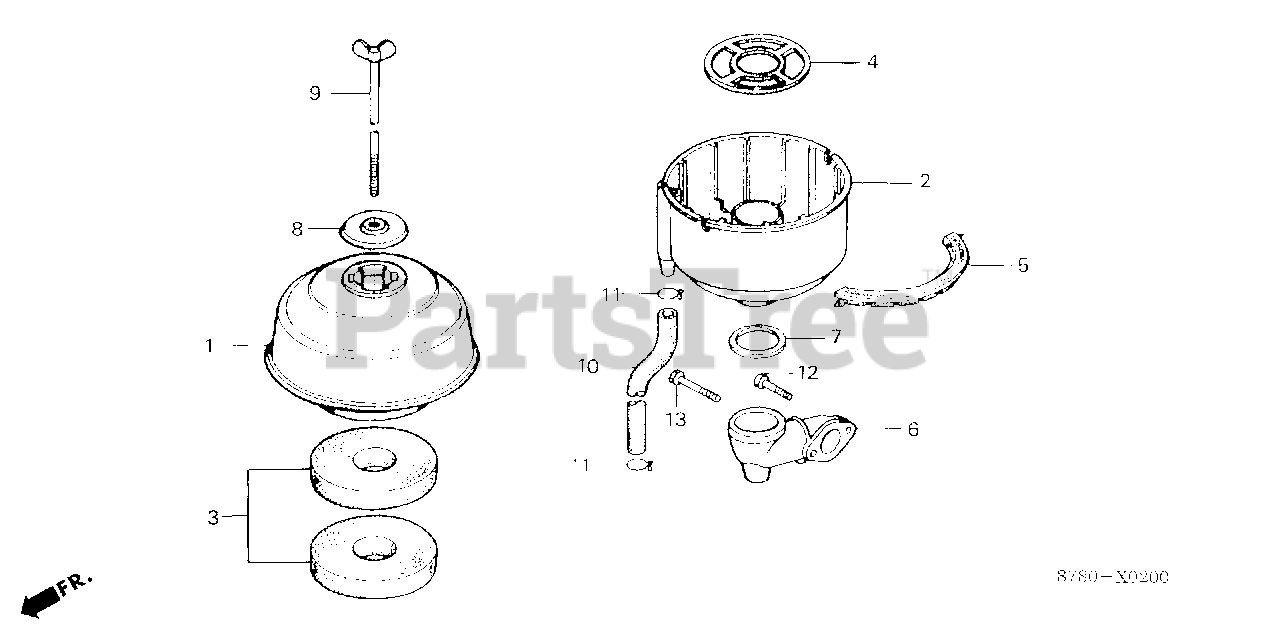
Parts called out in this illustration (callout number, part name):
1	BODY, CLEANER
2	PAN, AIR CLEANER OIL (NOT AVAILABLE)
3	ELEMENT, AIR CLEANER
4	GRID, AIR CLEANER
5	GASKET, OIL CLEANER
6	ELBOW, AIR CLEANER
7	GASKET, IN. ELBOW (NOT AVAILABLE)
8	CAP, AIR CLEANER
9	BOLT, AIR CLEANER
10	BULK HOSE, FUEL (8X1000) (8X250)
11	CLIP, TUBE (B12.5)
12	BOLT, FLANGE (6X25)
13	BOLT, FLANGE (6X45)
